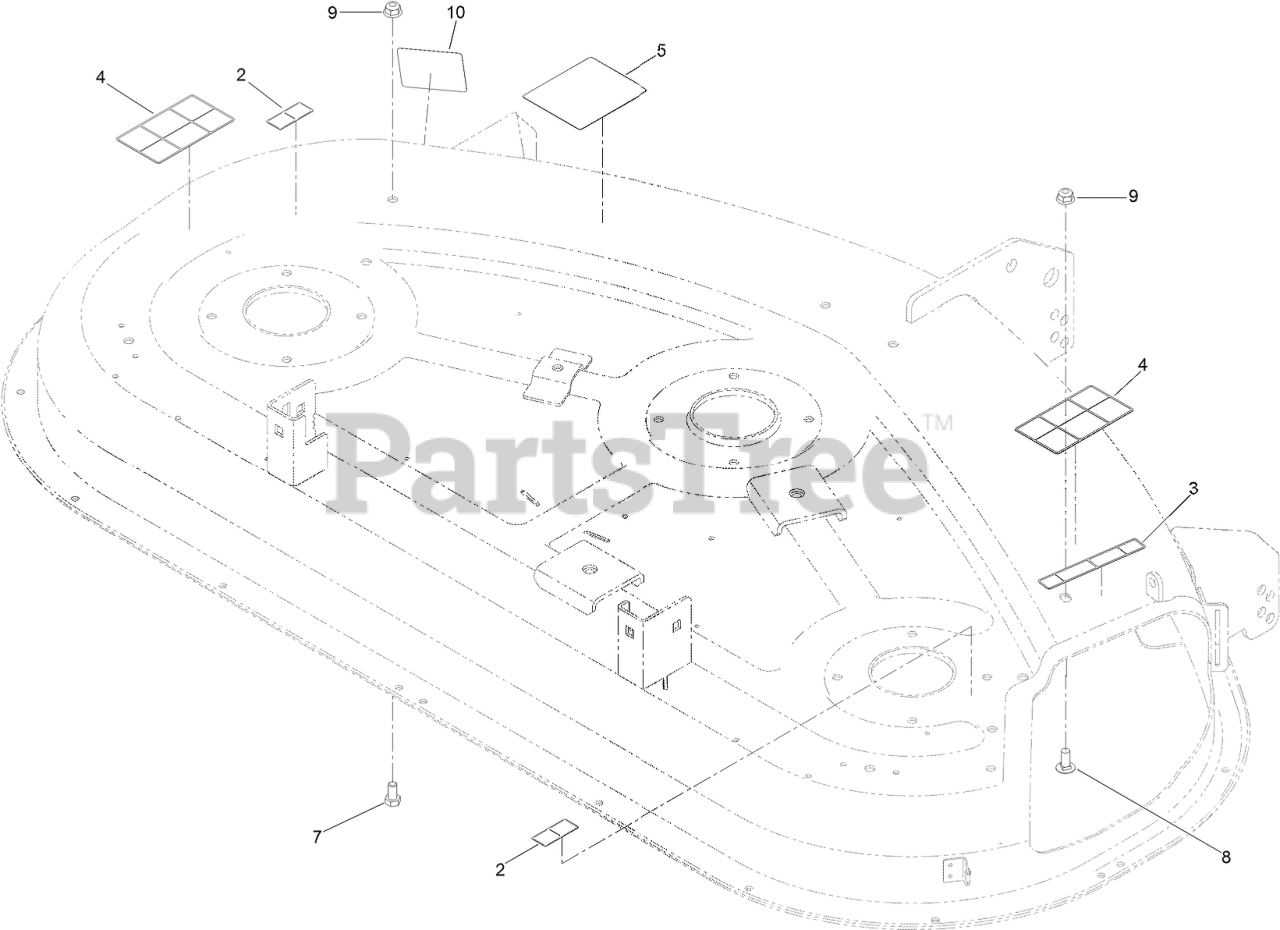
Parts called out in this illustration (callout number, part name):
2	DECAL-DANGER
3	DECAL-DANGER
4	DECAL-DANGER
5	DECAL-ROUTING, BELT
7	SCREW-HH
8	SCREW-CARR
9	NUT-HF, NI
10	DECAL-SCALP, ANTI
